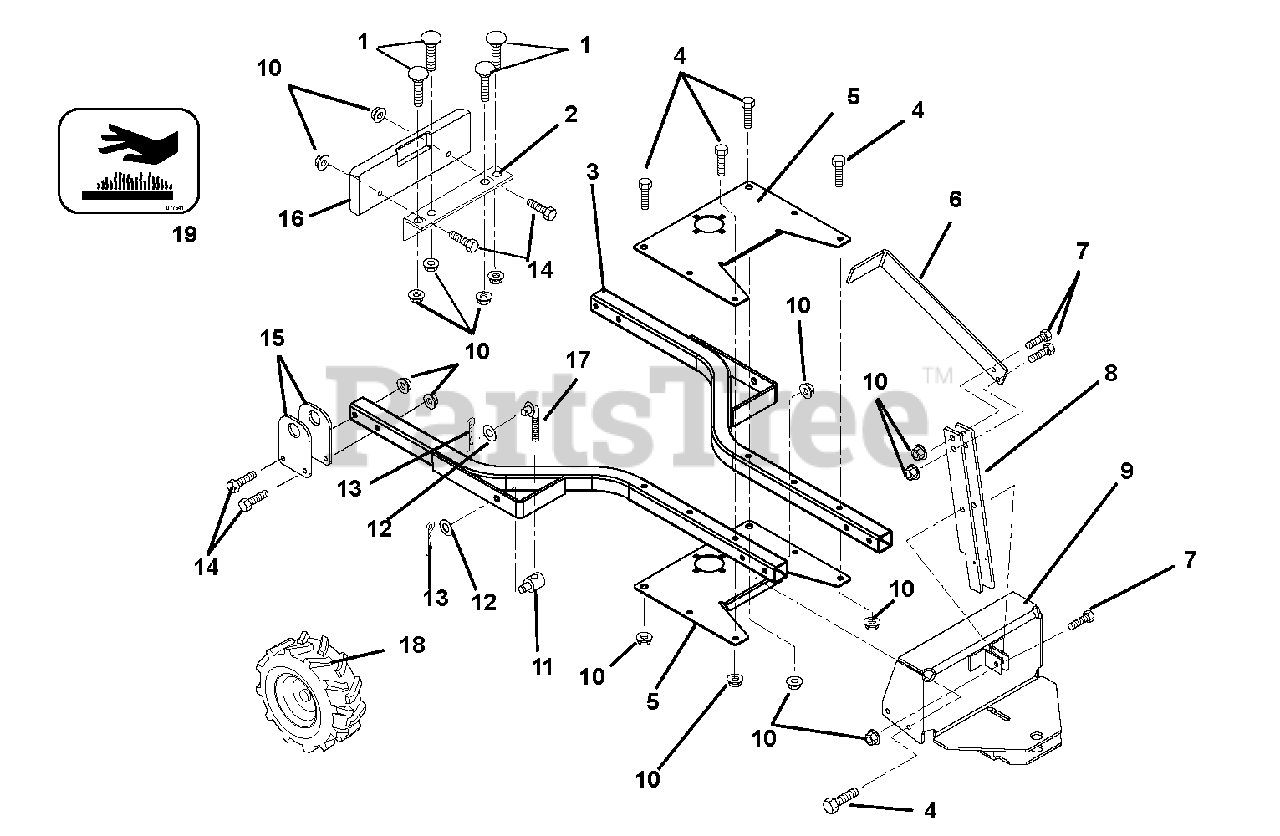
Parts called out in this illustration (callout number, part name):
1	Bolt, Round Head Square Neck, .38-16 x 2.50 Grade 5
2	Angle Bracket
3	Sub-Frame Tube
4	Hex Bolt, .38-16 x 2.25 Gr 5
5	Sub-Frame Plate
7	Hex Bolt, .38-16 x 1.25 Gr 5
9	Blade Mount Yoke
10	Top Locking Flange Nut, .38-16
11	Trunnion
12	Flat Steel Washer, .531 x 1.250 x .100
13	External Hair Pin, #16 Black Zinc
14	Hex Bolt, .38-16 x 2.5 Gr 5
15	Pivot Bracket
16	Weight, Cast Iron
17	Lift Link
18	Tire/Wheel Assembly, 18 x 16.5
19	Decal, Hot Surface
